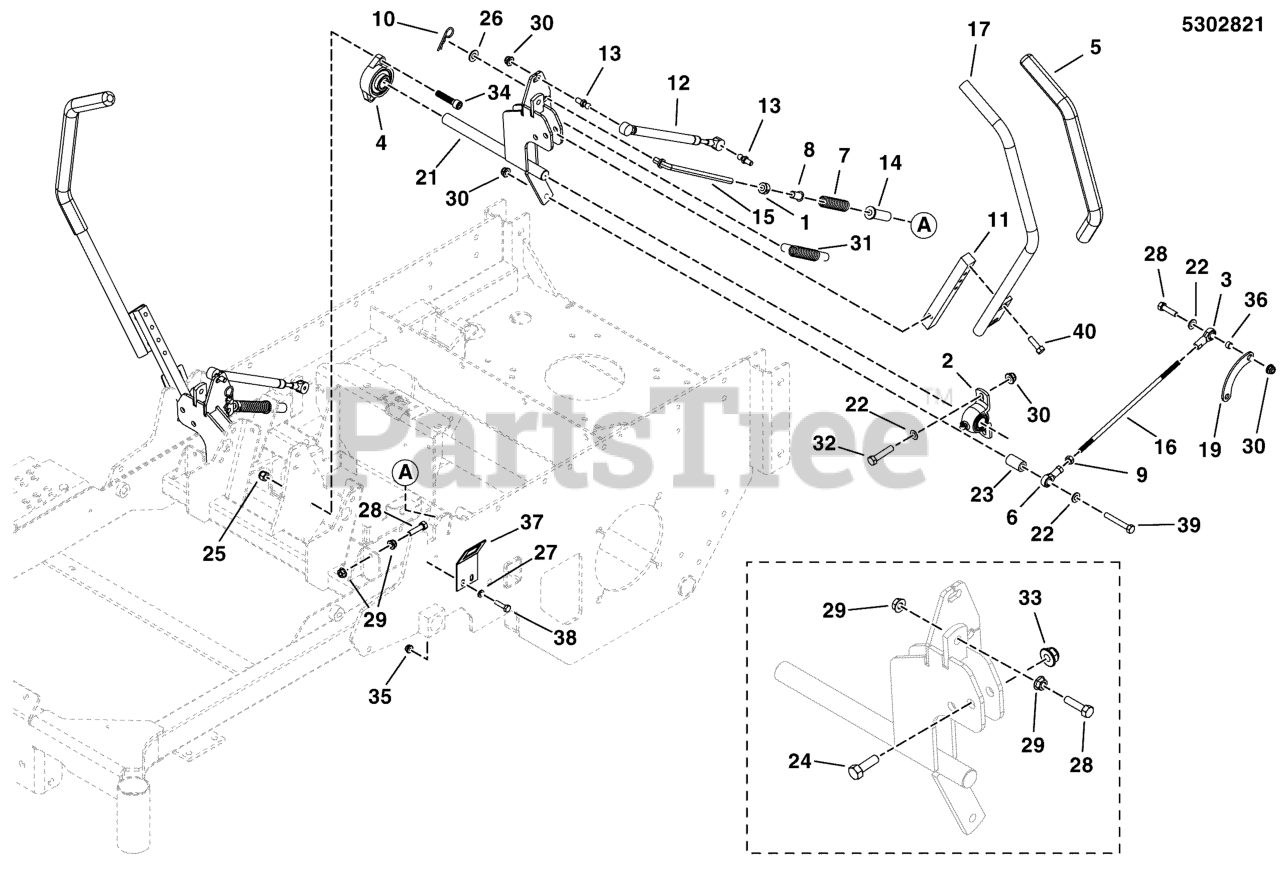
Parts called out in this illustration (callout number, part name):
1	COLLAR, 3/8 SET
2	BEARING, 3/4" PILLOW BLOCK
3	BALL JOINT 5/16-24 RH FEMALE BRONZE RACE
4	BEARING, FLANGE
5	GRIP, FOAM, 3/4 ID, 16 LONG
6	BALL JOINT 5/16-24 LH FEMALE BRONZE RACE
7	SPRING, REVERSE RETURN
8	BUSHING, FLANGE 3/8ID X 7/8 LONG
9	NUT, 5/16-24 HEX
10	PIN, HAIR, .0915 X 1-7/8
11	MOUNT, CONTROL ARM - BLK
12	DAMPENER, CONTROL,#(P6709/P3610)
13	BALL STUD, 5/16 X .50,# PC-477-2)
14	FLANGED BUSHING, 3/8IDX.63ODX.8125FL
15	ROD, NEUTRAL RETURN
16	ROD, HYDRO LINKAGE
17	WELD, HANDLE MOTION CONTROL LH - BLK
19	PLATE, HYDRO CONNECTOR - RED
21	WELD, CONTROL SHAFT, LH, SNP 2552 - BLK
22	WASHER, 5/16" SAE
23	SPACER, .38 X .75 X 1.25, CZ
24	BOLT, 3/8-16 X 1-3/4" GD5 CZ
25	NUT, 3/8-16 HEX NYLON LOCK
26	WASHER, 3/8 SAE
27	WASHER, 1/4 SAE
28	BOLT, 5/16-18 X 1-1/4 GD5 YZ
29	NUT, 5/16-18 HEX SERRATED FLANGE (SMALL)
30	NUT, 5/16-18 HEX NYLOCK FLANGE
31	SPRING-EXT, .500 OD X 3.50 LG X .058 WR
32	BOLT, 5/16-18 X 1 GD5 YZ
33	NUT, 3/8-16 HEX NYLOCK FLANGE
34	BOLT, 3/8-16 X 1-3/4, SHCS, YZ
35	NUT, 1/4-20 HEX NYLOCK FLANGE
36	SPACER, .328 X .425 X .250, CZ
37	SWITCH PLATE, MOTION CONTROLS - RED
38	BOLT, 1/4-20 X 1" GD5 CZ
39	BOLT, 5/16-18 X 2-1/4 GD5 YZ
40	SCREW-HEX WSHR HD TAPTT5/16-18X0.750BLK
